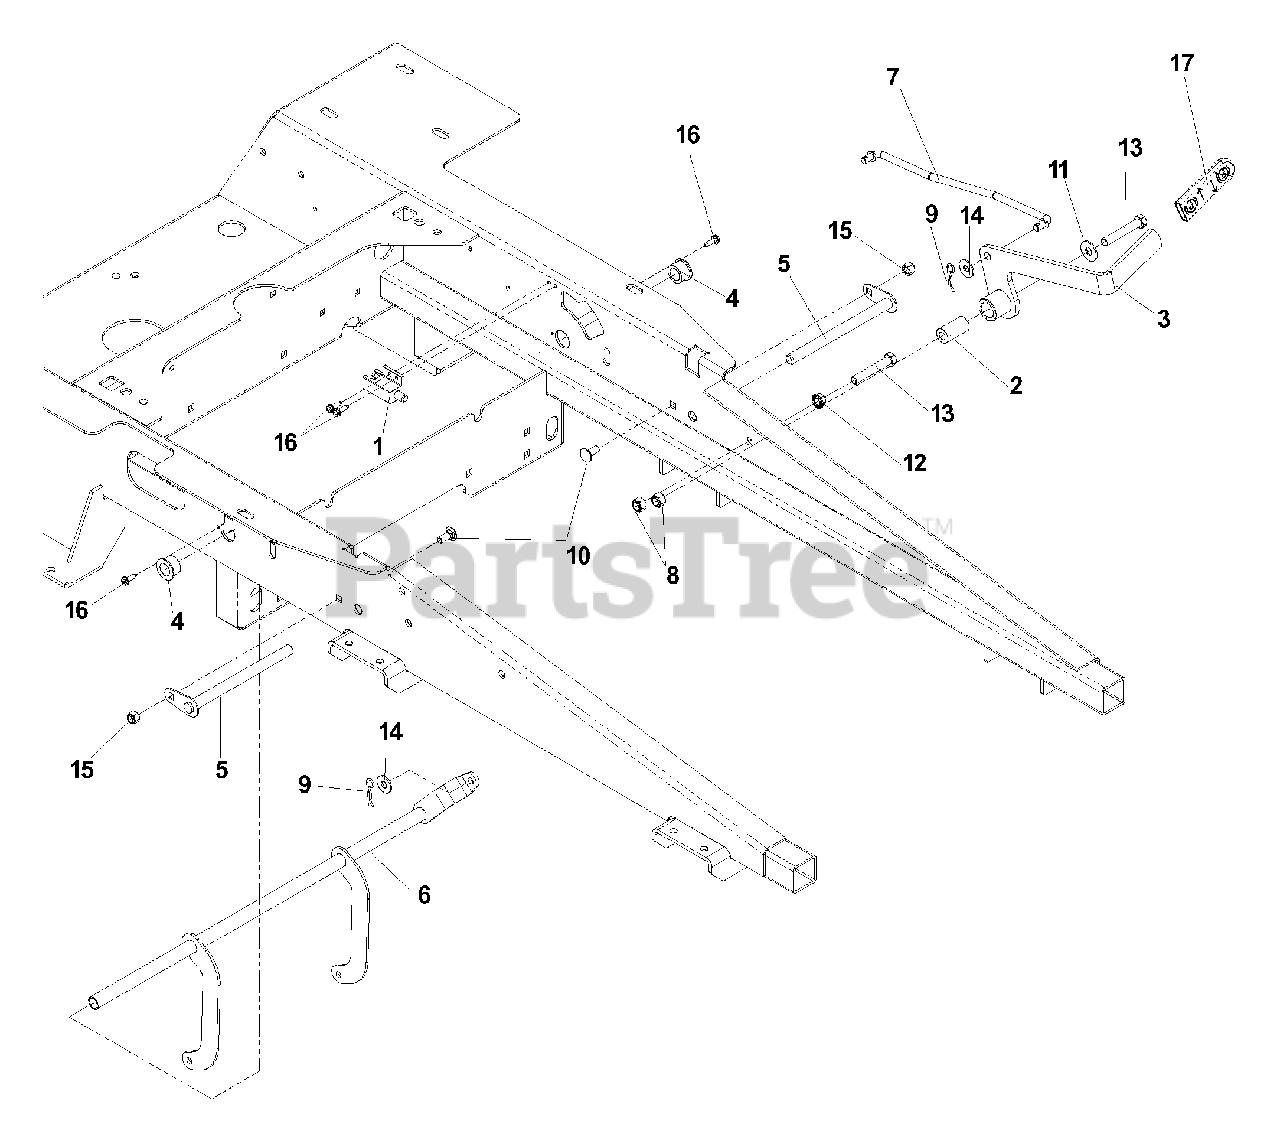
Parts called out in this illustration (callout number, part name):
1	SWITCH, INTERLOCK
3	BRAKE LEVER
4	BUSHING, PLASTIC
5	PIVOT SHAFT
6	BRAKE SHAFT
8	NUT, 3/8-16, NYLOC
9	PIN, HAIR, .073 X 1 7/16
10	RHSNB, 5/16-18 X 3/4, GR5
11	WASHER, 3/8
12	NUT, 5/16-18, WHIZLK
13	HCS, 3/8-16 X 2 1/4, GR5
14	WASHER, 5/16
15	NUT, 5/16-18, NYLOC
16	SCREW, #10-24 X 5/8, WASHER HD
17	GRIP, PARK BRAKE
